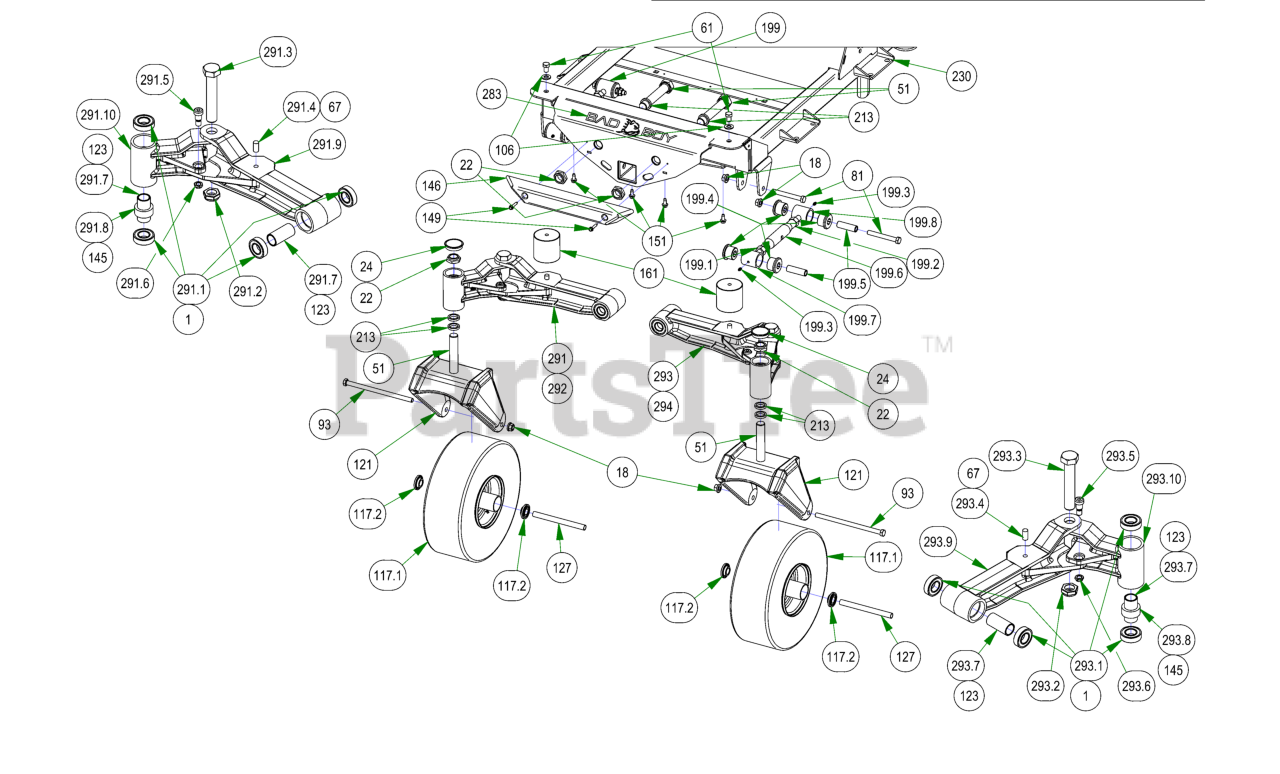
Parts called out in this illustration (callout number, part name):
1	1641 BEARING W/2 CONTACT RUBBER SEALS
18	1/2-13 NYLON INSERT FLANGE LOCKNUT ZINC
22	1"-14 NYLON INSERT JAM LOCKNUT ZINC
24	2017 Bearing Cover
51	1"-14 X 5-1/2 HEX CAP SCREW (GR.8) ZINC YELLOW
61	1/2-13 X 3/4 HEX CAP SCREW (GR.5) ZINC
67	1/2-13 x 1" Stud
81	1/2-13 X 4 HEX CAP SCREW (GR.8) ZINC YELLOW
93	1/2-13 X 9 HEX CAP SCREW (GR.5) ZINC
106	1/2 SAE FLAT WASHER (1-1/16" OD) GR.8 ZINC YELLOW
117	2019 15x6.00-6 Non Pneumatic Black Front Assembly
117.1	15x6-6 Tire Only
117.2	1-3/4" Bearing-Large Bore Front Rim
121	2020 R Series Cast Front Fork
123	2016 Front Bearing Spacer
127	Front Wheel Spanner
145	Rubber Stabilizer (Front Forks) [R series]
146	2017 XP Bumper
149	1/4-14 X 1-1/2 HEX WASHER UNSLOT TEK/3 ZINC
151	5/16-18 X 3/4 HEX WASHER SLOT (F) TCS ZINC
161	Vibration Mount-Blue Dot
199	Turnbuckle
199.1	11/16-12 Hex Nut-2015 Toplink
199.2	11/16-12 Lefthand Hex Nut-Topl
199.3	1/4" Press in Grease Fitting
199.4	Polyeurethane Bushing
199.6	2015 Outlaw Toplink Body
199.7	2015 Outlaw Toplink RH End
199.8	2015 Outlaw Toplink LH End
213	1.02 ID X 1.38 OD X .250 THK SPACER ZINC
230	2021 Rogue Suspension Frame Painted
283	Flying Bulldog Front Bumper Decal
291	2022 61/72 Rogue/Renegade Front Suspension Asy RH
291.1	1641 BEARING W/2 CONTACT RUBBER SEALS
291.2	1" Fine Thread 1/2 Nylock Nut
291.3	1"-14 X 5-1/2 HEX CAP SCREW (GR.8) ZINC YELLOW
291.4	1/2-13 x 1" Stud
291.5	5/8 X 5/8 SOCKET SHOULDER BOLT ZINC YELLOW
291.6	1/2-13 NYLON INSERT JAM LOCKNUT ZINC
291.7	2016 Front Bearing Spacer
291.8	Rubber Stabilizer (Front Forks) [R series]
291.9	INNER RH FRONT AXLE
291.10	OUTER FRONT ARM RH
292	2019 Front I-Beam Left - Black
293	2022 61/72 Rogue/Renegade Front Suspension Asy LH
293.1	1641 BEARING W/2 CONTACT RUBBER SEALS
293.2	1" Fine Thread 1/2 Nylock Nut
293.3	1"-14 X 5-1/2 HEX CAP SCREW (GR.8) ZINC YELLOW
293.4	1/2-13 x 1" Stud
293.5	5/8 X 5/8 SOCKET SHOULDER BOLT ZINC YELLOW
293.6	1/2-13 NYLON INSERT JAM LOCKNUT ZINC
293.7	2016 Front Bearing Spacer
293.8	Rubber Stabilizer (Front Forks) [R series]
293.9	INNER FRONT ARM LH
293.10	CAST OUTER ARM LH
294	R.H. I-BEAM ARM - Black
